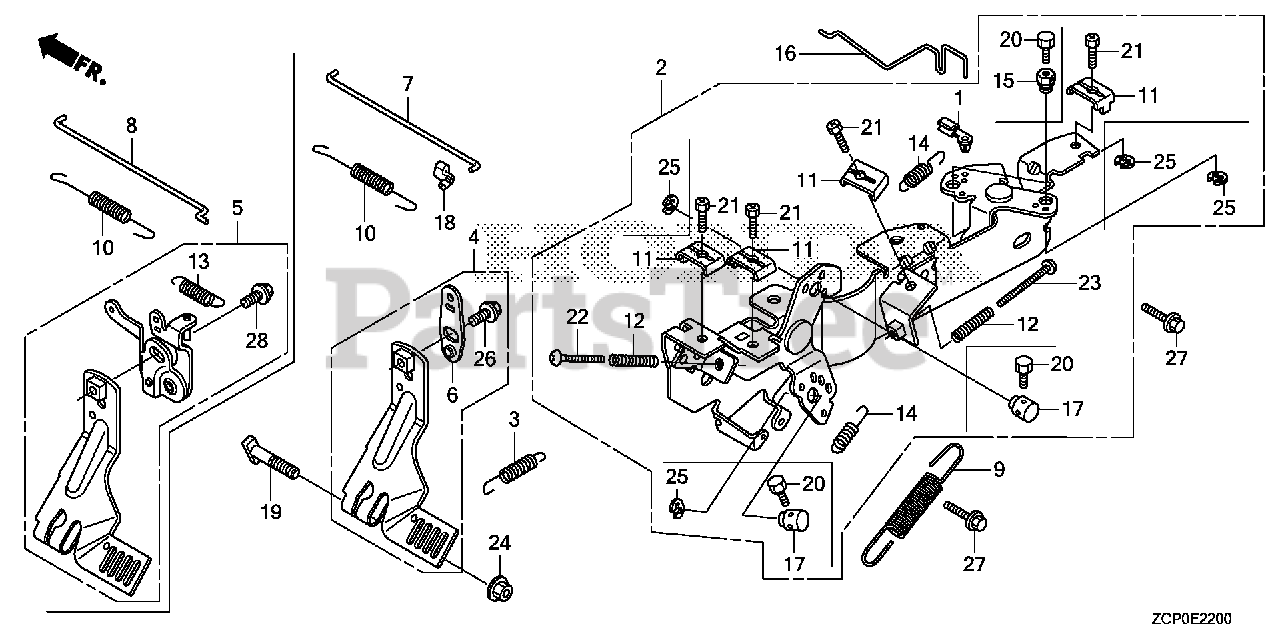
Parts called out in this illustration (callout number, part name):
1	JOINT, ROD
2	CONTROL ASSY.
3	SPRING, STARTER
4	ARM, GOVERNOR
6	ARM, SUB
7	ROD, GOVERNOR
9	SPRING, GOVERNOR
10	SPRING, THROTTLE RETURN
11	HOLDER, CABLE
12	SPRING, CONTROL ADJUSTING
14	SPRING, CABLE RETURN
16	ROD, CHOKE CONTROL
17	HOLDER, CABLE
18	BUSH, LINKAGE
19	BOLT, GOVERNOR ARM
20	BOLT, RECESSED (4X6)
21	BOLT, RECESSED (5X16)
22	SCREW, PAN (5X30)
23	SCREW, PAN (5X45)
24	NUT, FLANGE (6MM)
25	E-RING (5MM)
26	BOLT, FLANGE (6X10)
27	BOLT, FLANGE (6X14)
